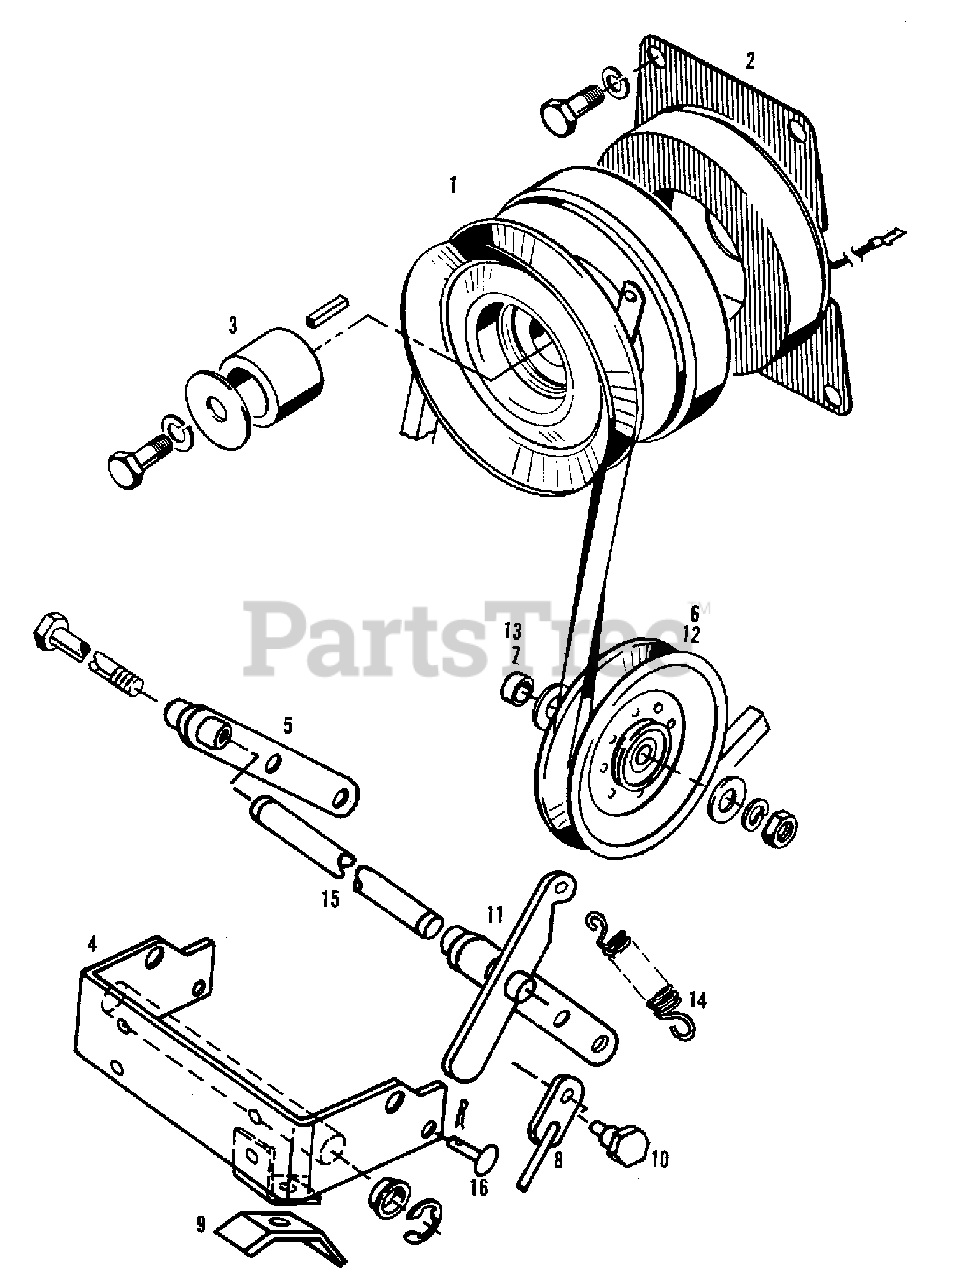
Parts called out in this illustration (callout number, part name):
1	HUB, Electric Clutch
1	KEY, 1/4 x 1/4 x 5/8 Parallel
2	COIL, Clutch
3	WASHER, 1/2 x 1-1/2 x 10 Ga.
3	LOCKWASHER, 7/16
3	CAPSCREW, 7/16NF x 1-1/4
3	CAPSCREW, 7/16NC x 5/8
4	BRACKET ASSEMBLY, P.T.O.
5	ARM ASSEMBLY, Idler
6	PULLEY, Idler
7	CAPSCREW, 3/8NC x 1-3/4
7	WASHER, 13/32 x 7/8 x 14 GA
7	LOCKWASHER, 3/8
7	NUT, 3/8NC
8	LINK, Adjusting
8	NUT, 7/16NF
8	LOCKWASHER, 7/16
9	NUT, Wing
10	BOLT, Shoulder
10	LOCKWASHER, 3/8
10	NUT, 3/8NC
11	LEVER ASSEMBLY
12	PULLEY, Idler
13	CAPSCREW, 3/8NC x 1-3/4
13	WASHER, 13/32 x 7/8 x 14 GA
13	NUT, 3/8NC
13	PIN, 3/16 x 1
13	LOCKWASHER, 3/8
14	SPRING, P.T.O. Extension
15	SHAFT, Idler Support
15	WASHER, .641 x 1-1/4 x 16 Ga.
16	PIN, 3/8 x 1-1/2 Round Head
16	PIN, Quick Hitch
17	TRANSFER P.T.O.
